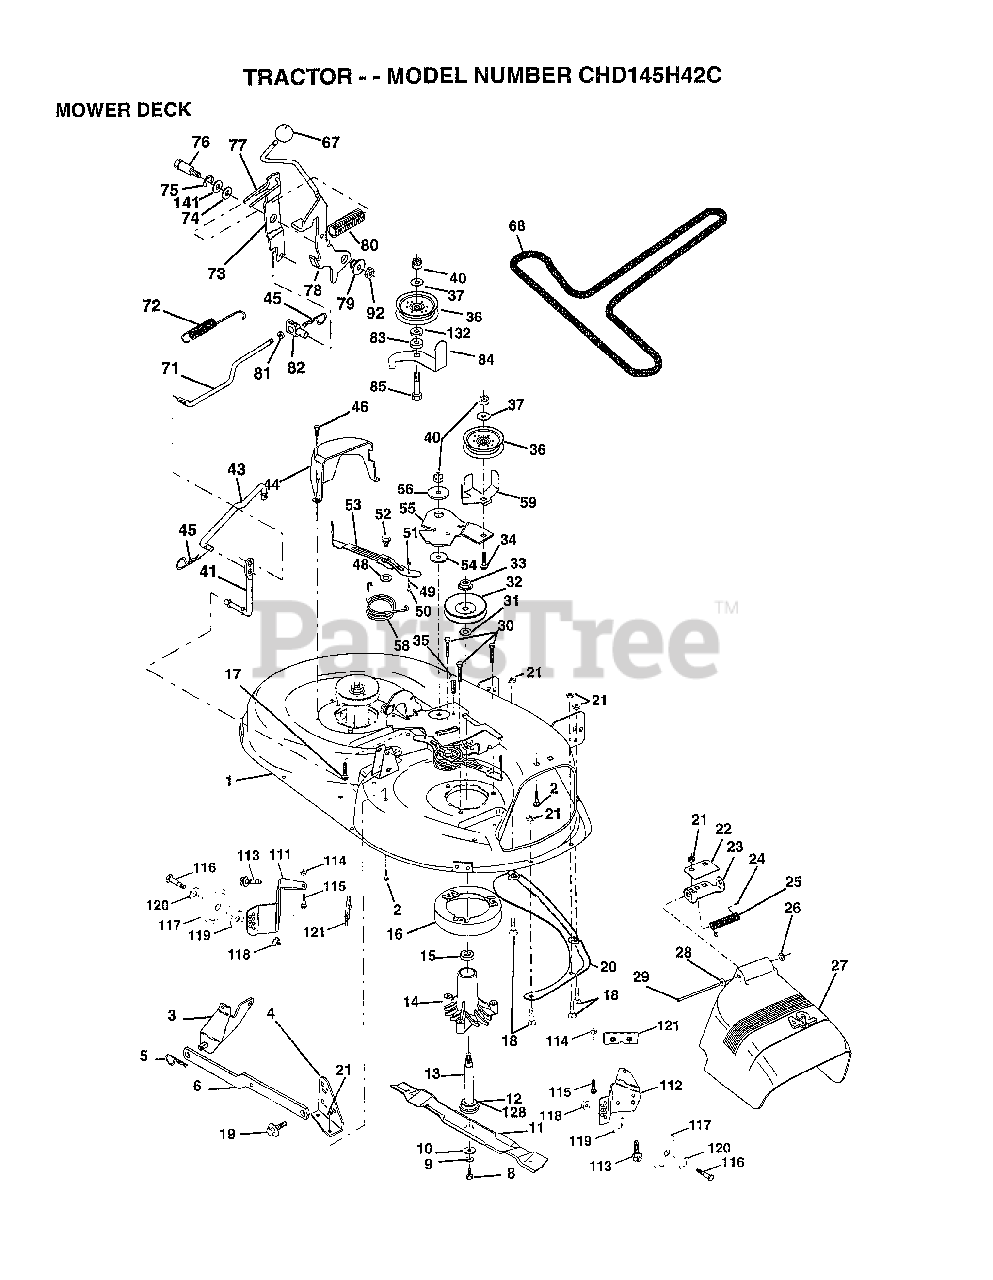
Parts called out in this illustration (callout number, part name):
1	DECK.WELD.42.
2	BOLT
3	BRKT ASM SWAY BAR
4	BRKT DECK SW BAR
8	BLADE BOLT
10	WASHER.HARD.BLADE
11	"BLADE.42"" HIPERF"
12	BEARING.BALL
14	HSG ASM MANDREL
15	BEARING
16	STRIPPER RND MWR
17	BOLT RDHD 3/8-16
18	BOLT
19	BOLT SHD 5/16-18
20	BAFFLE VORTEX 42
22	STIFFENER BRKT
23	DEFLECTOR BRKT
25	SPRING TORSION
27	DEFLECTOR.SHIELD
28	WASHER
29	HINGE ROD
30	"SCREW-THD ROLL,WA"
31	WASHER
32	PULLEY.MANDREL.42
34	BOLT
35	XMAS TREE FASTNER
36	FLAT IDLER PULLEY
37	WASHER
41	PIVOT ROD
43	ROD CLUTCH W/NIBS
44	GUARD MAND LH BLK
46	SCREW.1/4-20X5/8
48	HARD SMALL WASHER
49	ROLLER ASM-CAM
50	SHOULDER BOLT
51	LOCKNUT
52	BOLT.SHLD.5/16-18
53	BRAKE PAD ARM ASM
54	HARDENED WASHER
55	ARM-IDLER
56	SPACER RETAINER
58	SPRING TORSN BRAK
59	GUARD IDLER TUV
67	KNOB.RD.7/16-14
68	BELT.V.T-PATH
71	ROD CLUTCH 38/42
72	RETURN SPRING
73	CLUTCH ARM SECOND
74	WASHER
75	RING
76	SHOULDER BOLT
77	SPRING KEEPER
78	LEVER.ASM.CLUTCH
79	BUSHING
80	SPRING.CLUTCH.MWR
81	NUT
82	TRUNION ADJ
83	WASHER
84	"KEEPER-BELT,FIXED"
85	BOLT RDHD 3/8-16
92	NUT
111	BRACKET.GWHL.LH.
112	BRACKET.GWHL.RH.
113	SCREW
116	BOLT M
117	WHEEL.GAGE.BLK.PL
118	LOCKNUT
119	WASHER
120	WASHER
121	BRACKET.EXTRD.GWL
128	WASHER.FELT.
132	WASHER GT
141	WASHER .T
